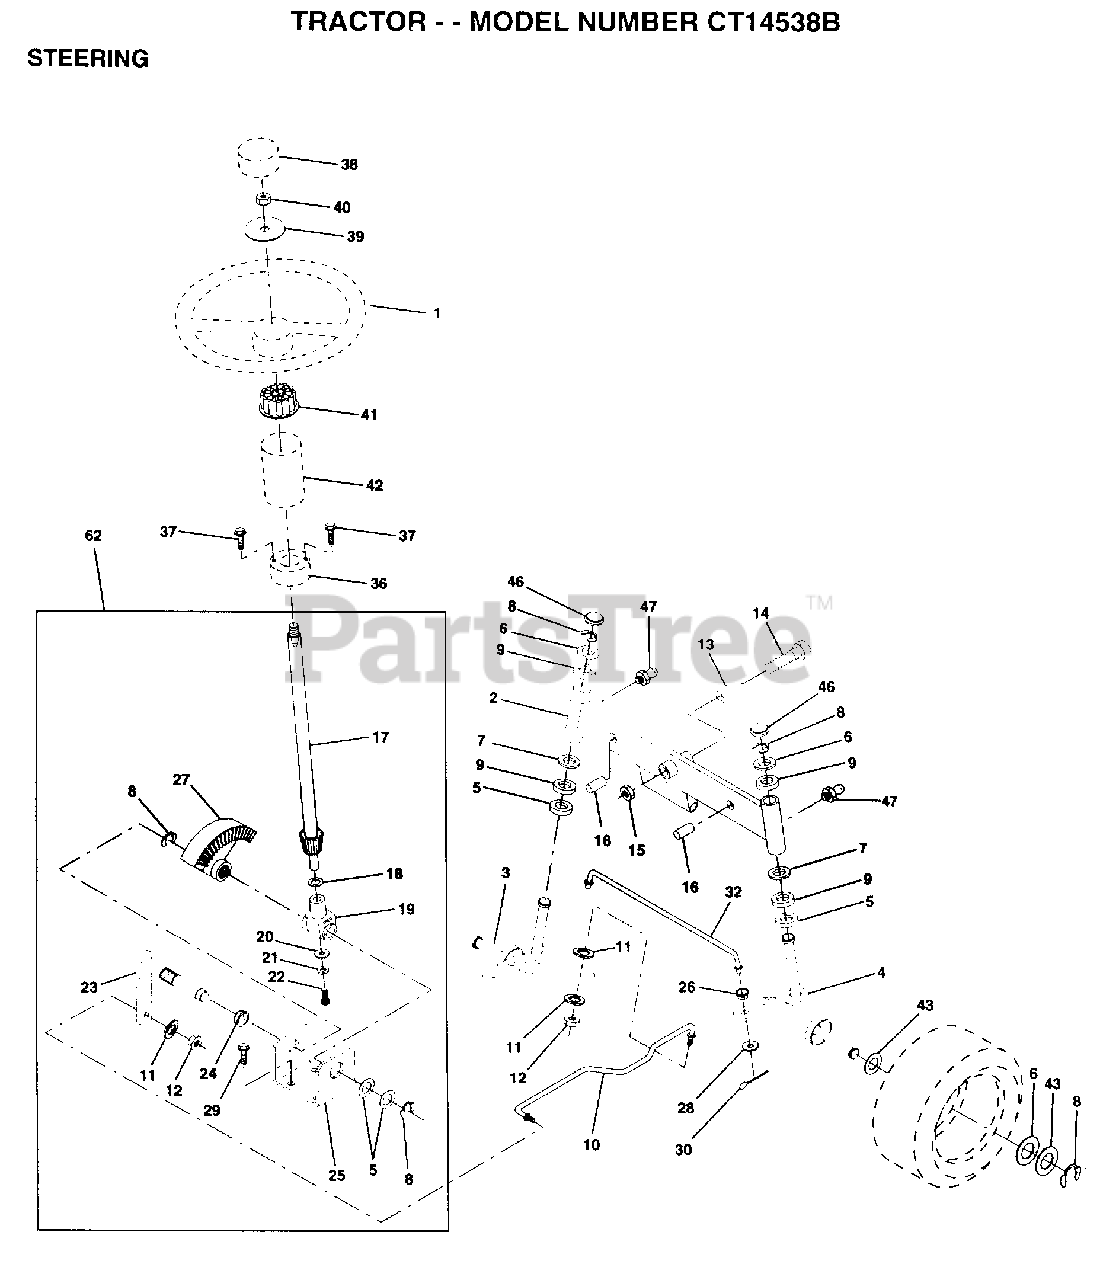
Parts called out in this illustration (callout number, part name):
2	AXLE ASM FRONT
3	SPINDLE LH
4	SPINDLE RH
5	WASHER .T
6	WASHER
7	WASHER
8	RING
9	COL. SRTG. BEAR.
11	LOCKWASHER
13	BEARING
14	BOLT HEX 5/8-11
15	"NUT-LOC,FLANGE LT"
16	AXLE PIN
17	SHAFT ASM
18	THRUST WASHER
19	SUPPORT.SHAFT
21	LOCKWASHER
22	SCREW.SCKTHD.CAP
24	NYLINER T
25	"BRKT,STEERING"
26	BUSHING.DRAGLINK
27	GEAR SECTOR
28	WASHER
29	SCREW
30	COTTER PIN
32	TIE ROD
38	ST WHL INSERT CAP
39	WASHER T
40	GRIPCO NUT
41	ADAPTER-WHEEL LT
42	"TUBE, STR SHAFT"
43	WASHER
46	CAP
47	ZERK M
